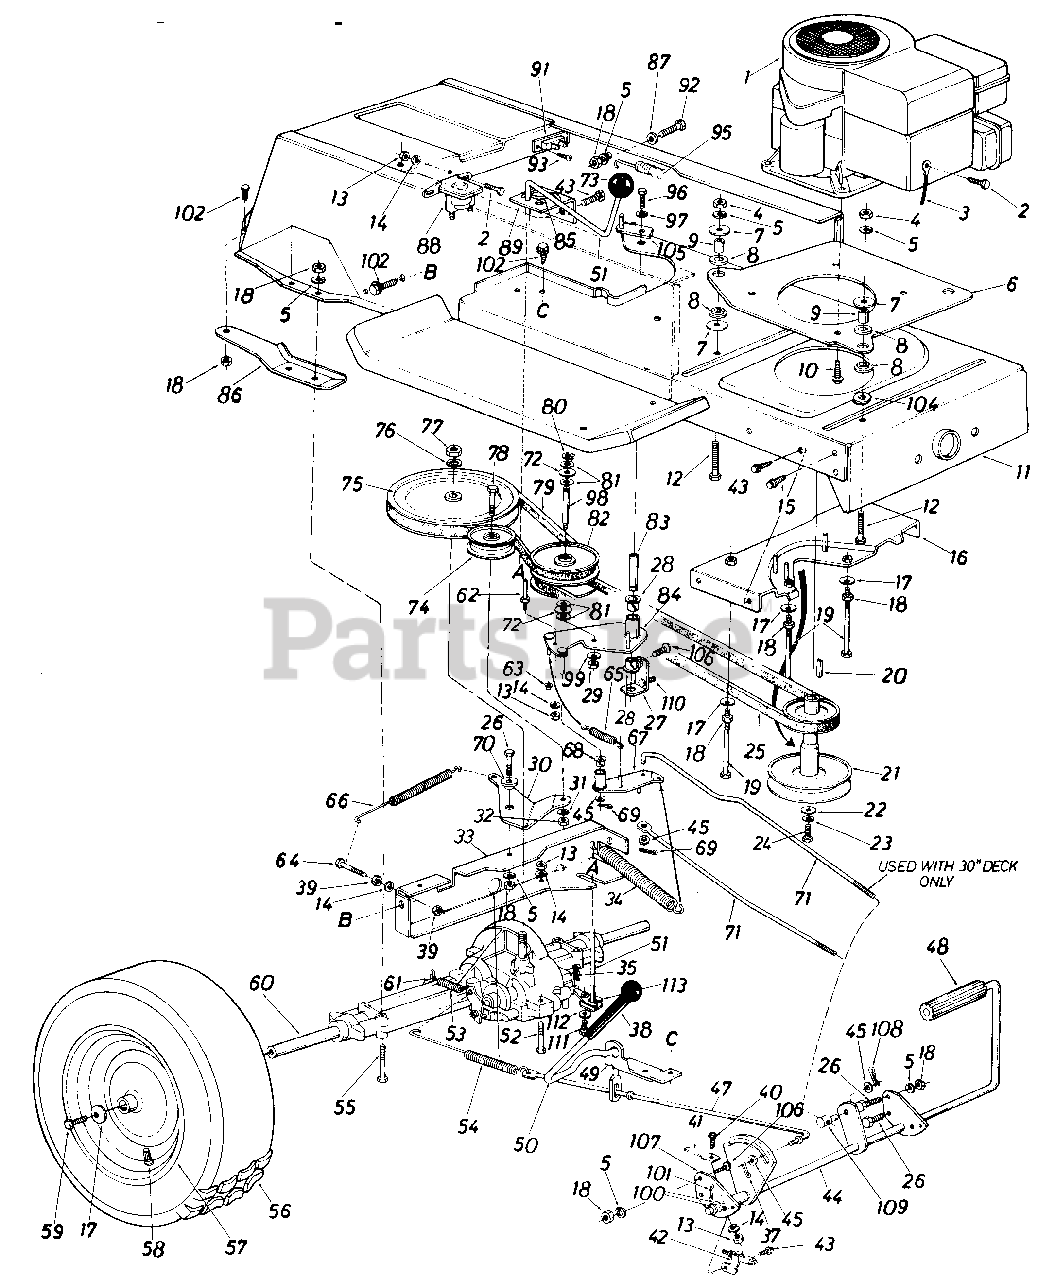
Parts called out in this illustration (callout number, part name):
1	Engine
2	Hex Bolt 1/4-20 x .62" Lg.*
3	Electric Ground Wire
4	Hex Nut 5/16-24 Thd.*
5	L-Wash. 5/16" I.D.*
6	Engine Mounting Plate
7	Fl-Wash. .320" I.D. x 1.25"
8	Engine Mounting Grommet
9	Spacer
10	Hex Bolt 3/8-16 x 1.25" Lg.
11	Lower Frame Ass'y.
12	Hex Bolt 5/16-24 x 1.25"*
13	Hex Nut 1/4-20 Thd.*
14	L-Wash. 1/4" I.D.*
15	Hex Wash. Hd. AB-Tap Scr. 5/16" x .75" Lg.
16	Belt Guard Brkt. Ass'y.
17	Bell-Wash. .345" I.D. x .88"
18	Hex Nut 5/16-18 Thd.*
19	Hex Bolt 5/16-18 x 5.25" Lg.
20	Sq. Key 1/4" x 1/4" x 2.00"
21	Engine Pulley 5.56" Dia. & 3.56" Dia.
22	Fl-Wash. 7/16" I.D. x 1.25"
23	L-Wash. 7/16" I.D.*
24	Hex Bolt 7/16-20 x 1.50" Lg.
25	Variable-Speed Belt .715 x 53" Lg.
27	Bearing Shaft Bracket Ass'y.
28	Flanged Nyliner Brg. 5/8" I.D. x .88" Lg.
29	Hex Nut 3/8-24 Thd.*
30	Idler Bracket
31	L-Wash. 3/8" I.D.*
32	Hex Nut 3/8-24 Thd.*
33	Transaxle Support Brkt.
34	Ext. Spring .94" O.D. x 6.7
35	Inter. Cott-Pin
37	Cotter Pin 3/32" Dia. x .75"*
38	Grip-Black
39	Hex Nut 1/4-28 Thd.
40	Hex Bolt 1/4-20 x 1.00" Lg.*
41	Switch Actuator
42	Safety Switch
43	Hex Wash. Hd. S-Tap Scr. 1/4-20 x .50" Lg.
44	Clutch & Brake Pedal Ass'y.
45	Fl-Wash.
47	Brake Rod 20.9" Lg.
48	Foot Pad
49	Brake Lever Bracket
50	Hill Holder Brake Handle
51	Shift Lever Ass'y.
52	Hex Bolt 1/4-28 x 1.75" Lg.*
53	Ext. Spring .38" O.D. x 2.5"
54	Ext. Spring .59" O.D. x 7.08"
55	Hex Bolt 5/16-18 x 2.75"*
57	Wheel Rim Only
58	Air Valve
59	Hex Bolt 5/16-24 x .75" Lg.
60	Transaxle Complete
61	Brake Return Spring Anchor
62	Belt Guard Pin 1/4-20 Thd.
63	Cap Speed Nut 1/4" Dia.
64	Hex Bolt 1/4-28 x 1.25" Lg.
65	Ext. Spring .50" Dia.
66	Ext. Spring .62" O.D. x 6.12"
67	Variable Speed Torque Brkt. Ass'y.
68	Flanged Bearing
69	Cotter Pin 3/32" Dia.*
70	Shoulder Spacer .500" Dia. x .27" Lg.
71	Speed Control Link
72	Truss Bearing .56 Dia. x 1 .25"
73	Ball Knob
74	Fl-Idler Pulley 3.25" x 1.0"
75	1/2" "V"-Pulley 8.0" O.D. x .501 " I.D.
76	L-Wash. 1/2" I.D.*
77	Hex Jam Nut 1/2-20 Thd.*
78	Hex Bolt 3/8-24 x .75" Lg.
79	Variable Speed Belt .715 x 44" Lg.
80	Snap Ring .56" Dia.
81	Fl-Wash.
82	Variable Speed Pulley Ass'y. 5" O.D.
83	Bearing Shaft
84	Variable Speed Brkt. Ass'y.
85	Comp. Spring-Clip
86	Transaxle Support Brkt.-R.H.
87	Fl-Wash. .34 I.D. x 1.12 O.D.
88	Solenoid
89	Shift Lever Bracket
91	Circuit Breaker
92	Hex Bolt 5/16-18 x 1.50" Lg.
93	Truss Hd. Phil. Scr. #10 x 1/2" Lg
95	Ext. Spring .99" O.D. x 11.0"
96	Hex Bolt 3/8-24 x .75" Lg.*
97	Bell-Wash. .38" I.D. x .88"
98	Shaft .56" Dia. x 3.875" Lg.
99	8ell-Wash. .39" I.D. x 1.12"
100	Fl-Wash.
101	Cotter Pin 3132" Dia. x 1.0"*
102	Hex Wash. Hd. Scr. 5/16-18 x .62" Lg.
104	Fl-Wash. .32" I.D. x 1.25"
105	Belt Guard
106	Truss Mach. Scr. 5/16-18 x .75" Lg.*
107	Pedal Bracket
108	Cotter Pin 3132" Dia. x .75"
109	Ferrule
110	Truss Phillips Hd. Scr. 5/16-18 x 1.0" Lg.
111	Hex Bolt 1/4-28 x .50" Lg.
112	Bell-Wash. .265" I.D. x .75"
113	Shift Lever Link Ass'y.
